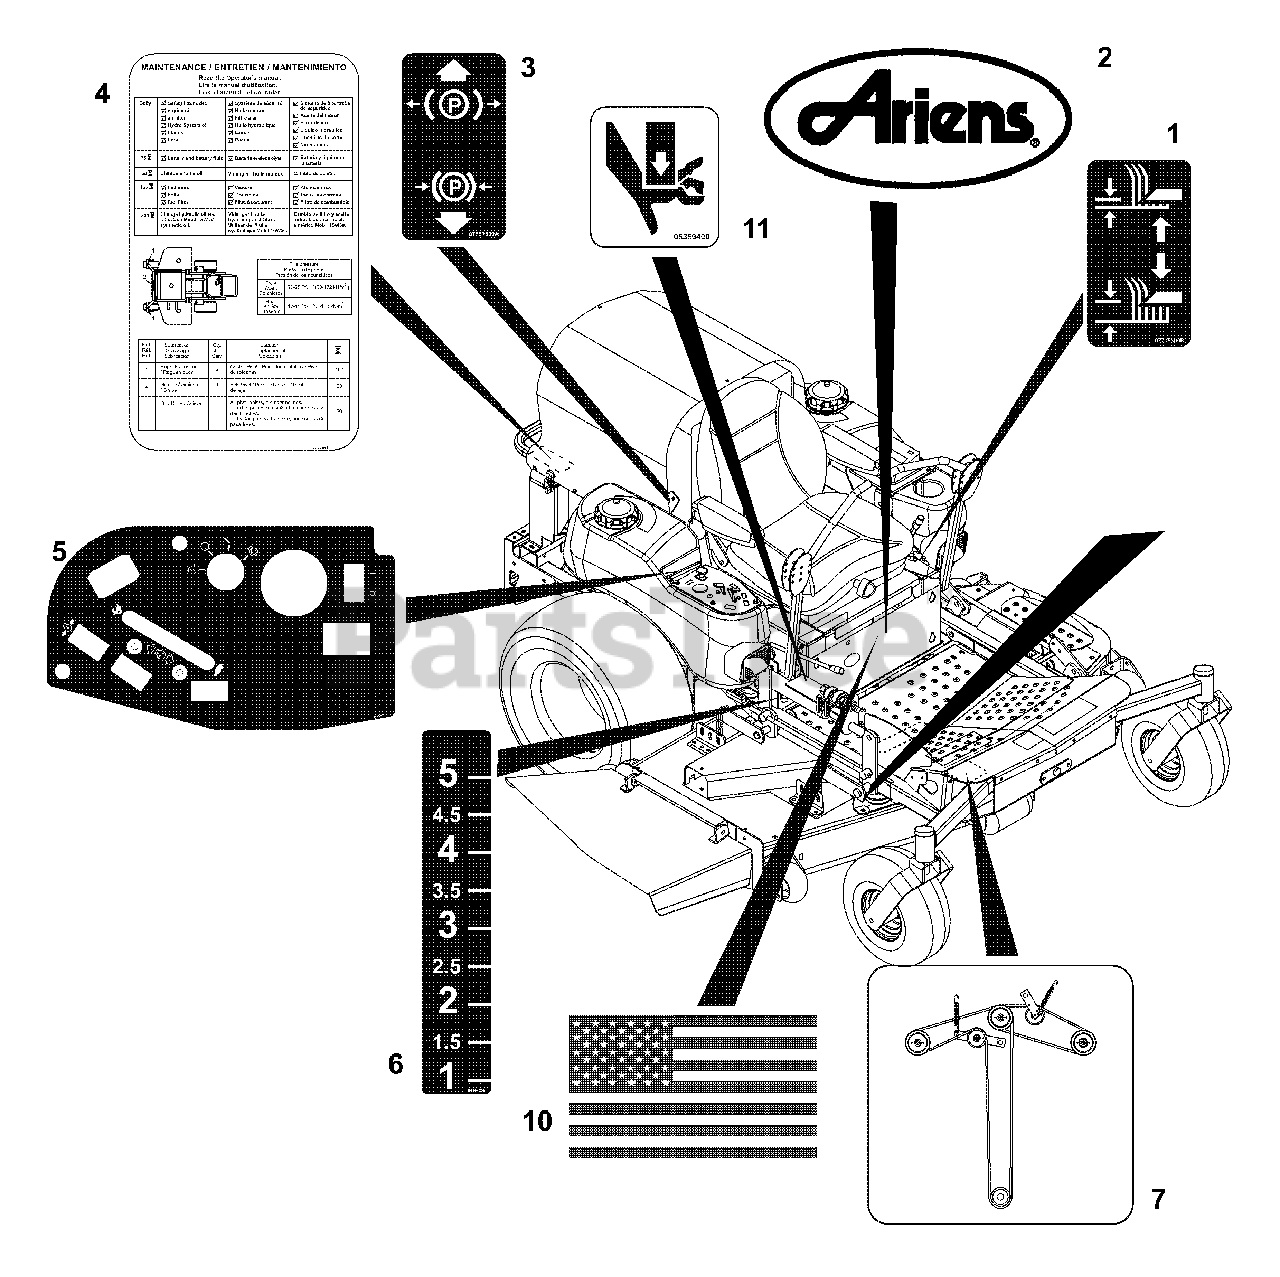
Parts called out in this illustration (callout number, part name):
1	DECAL- LIFT LEVER
2	DECAL, ARIENS
3	DECAL, PARKING BRAKE LEVER
4	DECAL- SERVICE INSTRUCTIONS
5	DECAL, CONTROL PANEL L/C - GAS
6	DECAL, HEIGHT OF CUT
7	DECAL, GRAVELY BELT DIAGRAM
8	DECAL, PM-260Z
9	DECAL, 60
10	DECAL, AMERICAN FLAG
11	DECAL, PINCH POINT
